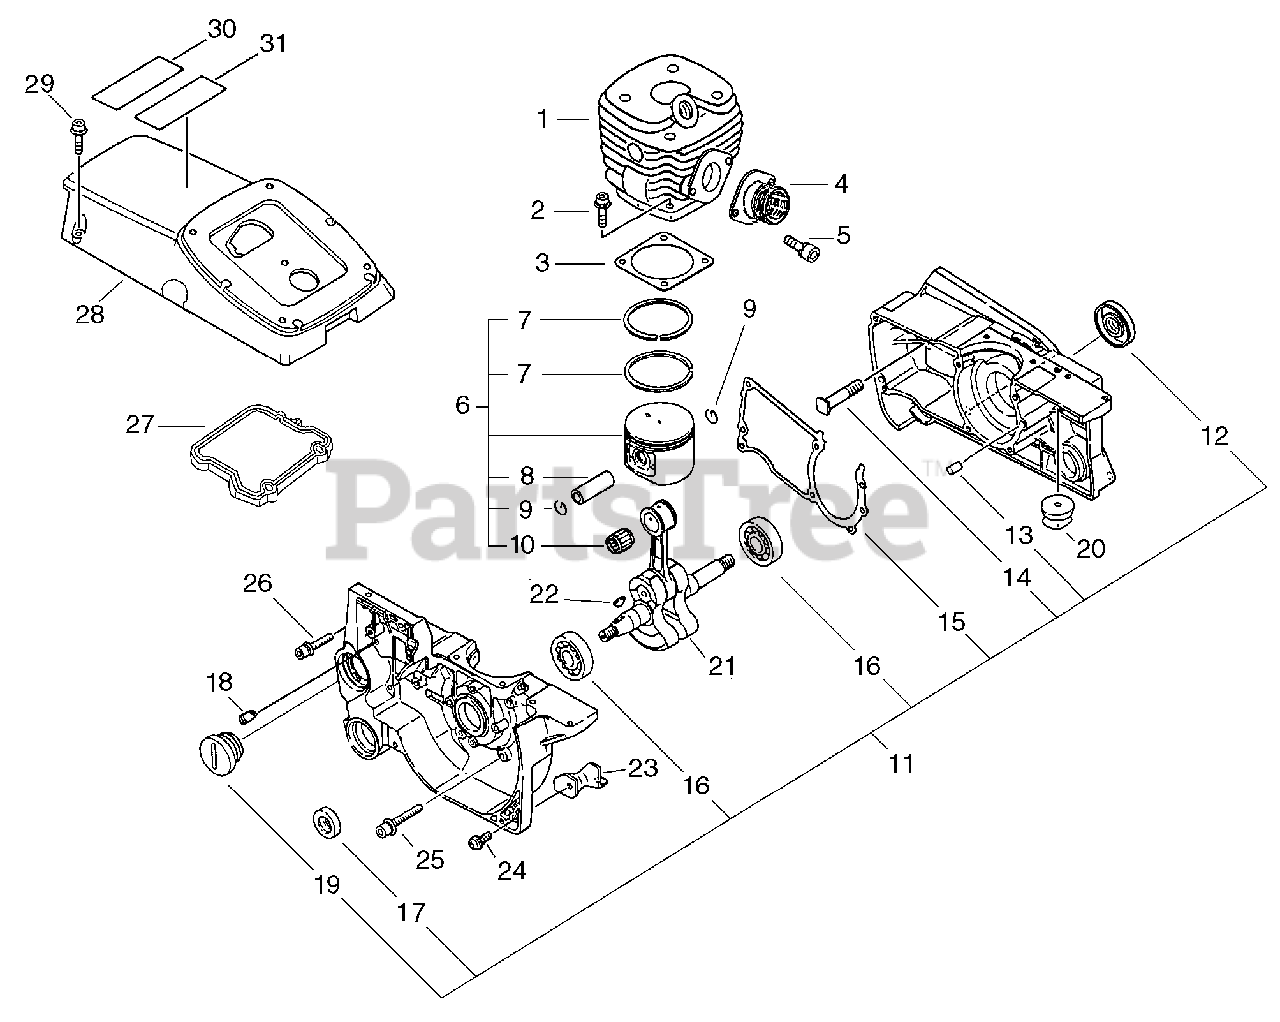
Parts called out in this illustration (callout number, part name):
1	CYLINDER
2	SCREW - 5X25
3	GASKET, CYLINDER
4	BELLOWS, INTAKE
5	SCREW - 4X14
6	PISTON KIT
7	RING, PISTON
8	PIN, PISTON
9	RING, RETAINING
10	BEARING, NEEDLE
11	CRANKCASE KIT
12	SEAL, OIL
13	PIN - LOCATING
14	STUD, GUIDE BAR
15	GASKET, CRANKCASE
16	BEARING, BALL - 6202
17	SEAL, OIL
18	VENT, TANK
19	CAP, OIL TANK
20	CUSHION - A
21	CRANKSHAFT ASSY
24	SCREW - 5X14
25	SCREW - 5X35
26	SCREW - 5X20
27	CUSHION
28	COVER, ENGINE
29	SCREW - 5X20
30	LABEL - CAUTION
31	LABEL - CAUTION
